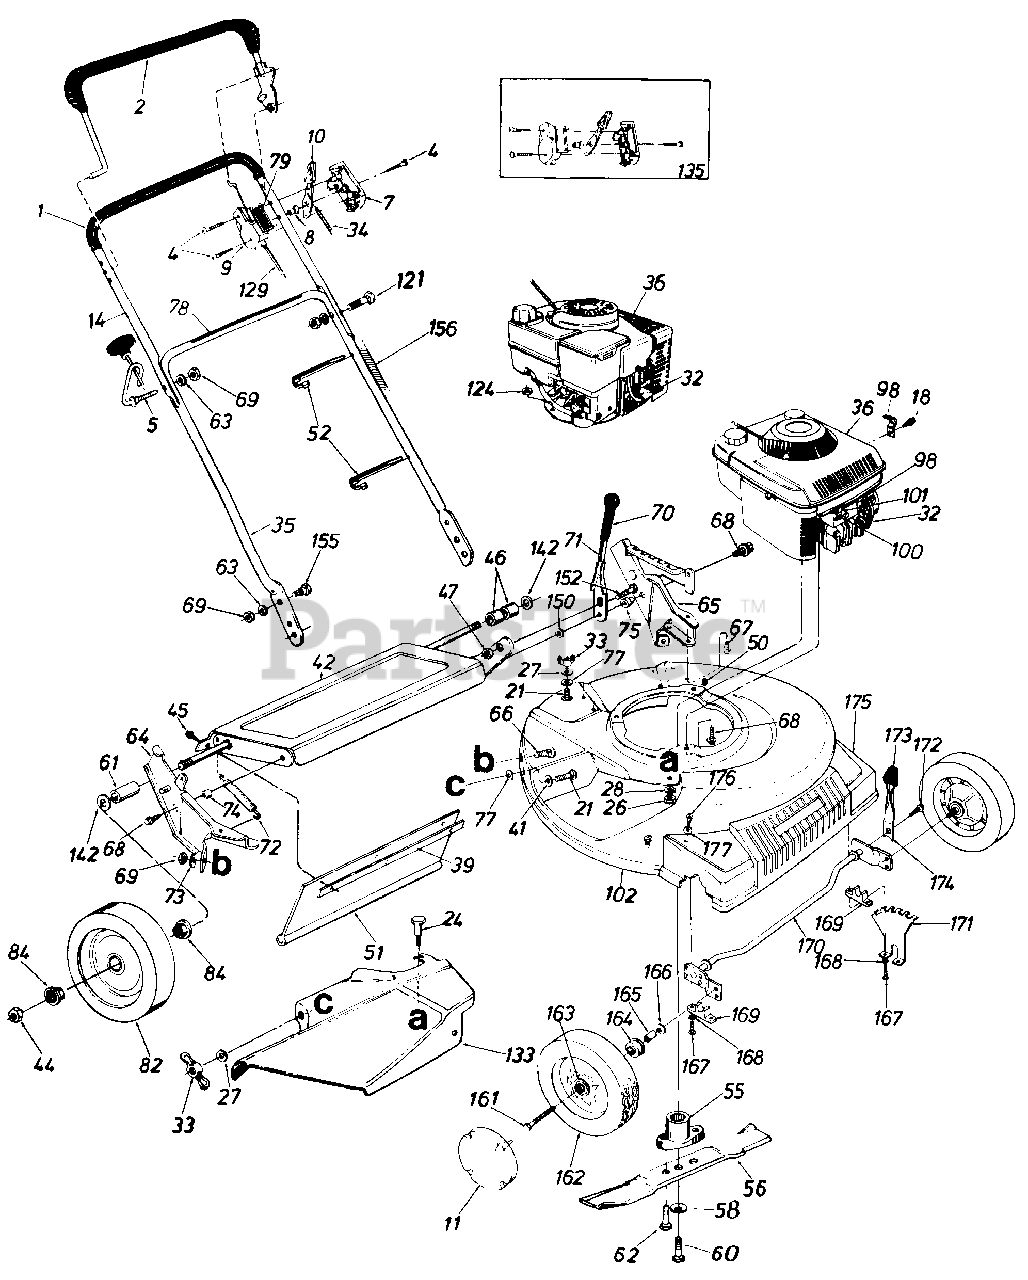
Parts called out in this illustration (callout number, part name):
2	Control Handle Ass'y. L.H.
4	Truss Mach. Scr. #12 x 1.50" Lg.
5	Rope Guide Bolt
7	Control Panel Half
8	Control Disc Pin
9	Clutch Panel Half
10	Throttle Control Lever
11	Hub Cap
14	Upper Handle Chrome
18	Hex B-Tap Scr. #10 x .38"
21	Carriage Bolt 1/4-20 x .62"
24	Shoulder Bolt .312 Dia. x .18 Lg. Special
26	Hex Nut 1/4-20 Thd.
27	Bell-Wash. 1/4" I.D.
28	L-Wash. 1/4" I.D.
32	Spark Plug Insulator
33	Wing Nut
34	Throttle Control Wire 58"
35	Lower Handle Chrome
36	Engine
39	Retaining Strip
41	Fl-Wash. .344" I.D. x .62"
42	Rear Axle Ass'y.
44	Hex L-Nut 1/2-20 Thd.
45	Hex AB-Tap Scr. 1/4 x .62"
46	Spacer.526" I.D.
47	Hex Patch L-Nut 3/8-24 Thd.
51	Rear Flap
52	Cable Tie
55	Blade Adapter
56	21" Blade
58	Bell-Wash. .460" I.D. x 1.38"
60	Hex Bolt 7/16-20 x 1.5"
61	Sleeve.526" I.D.
62	Hex L-Wash. Scr. 1/8-16 x .75"
64	R.H. Handle Wheel Brkt. Ass'y.
65	L.H. Handle Wheel Brkt. Ass'y.
66	Carriage Bolt 5/16-18 x .62"
67	Hex Wash. Hd. B-Tap Scr. 5/16-18
68	Hex Wash. Hd. TT-Tap Scr. 3/8-16
69	Hex Nut 5/16-18 Thd.
71	Height Adj. Lever
72	Extension Spring 3.80" Lg.
73	Bell-Wash. 5/16" I.D.
74	Spacer.385" I.D.
75	Shld. Spacer .5" Dia.
77	Bolt Retainer 1/4 x .50" O.D.
78	Instruction Label
79	Control Label
82	Wheel Ass'y. Comp. Rear
84	Flange Ball Bearing 1/2" I.D.
98	Casing Clamp
100	Hex B-Tap Scr. #10 x .62"
101	Casing Clamp
124	Hex Nut 3/8 x 16 Thd.
129	Control Cable 46"
133	Side Chute Deflector Ass'y.
135	Kit Control Housing Comp.
142	Fl-Wash. .510" I.D. x .75"
150	Fl-Wash. 3/8" I.D. x 1.0"
152	Hex Bolt 3/8-24 x .75" Lg.
155	Truss Mach. Scr. 5/16-18 x .75" Lg.
156	Plastic Tubing
161	Hex Bolt 3/8-16 x 1.75" Lg.
162	Wheel Ass'y. Comp. 8 x 1.75
163	Flange Ball Brg. 3/8" I.D.
164	Flange Ball Brg. .501" I.D.
165	Spacer
166	Bell-Wash. .400" I.D. x .88
167	Hex Wash. Hd. B-Tap Scr. 1/4-20
168	L-Wash. 1/4" I.D.
169	Block Bushing
170	Axle Ass'y.
171	Height Adj. Bracket
172	Hex Wash. Hd. B-Tap Scr. 1/4-20 x .75" Lg.
173	Knob
174	Spring Lever
175	Plastic Front End
176	Truss B-Tap Scr. 5/16 x .75" Lg.
177	Bell-Wash. 5/16" I.D. x 5/8
